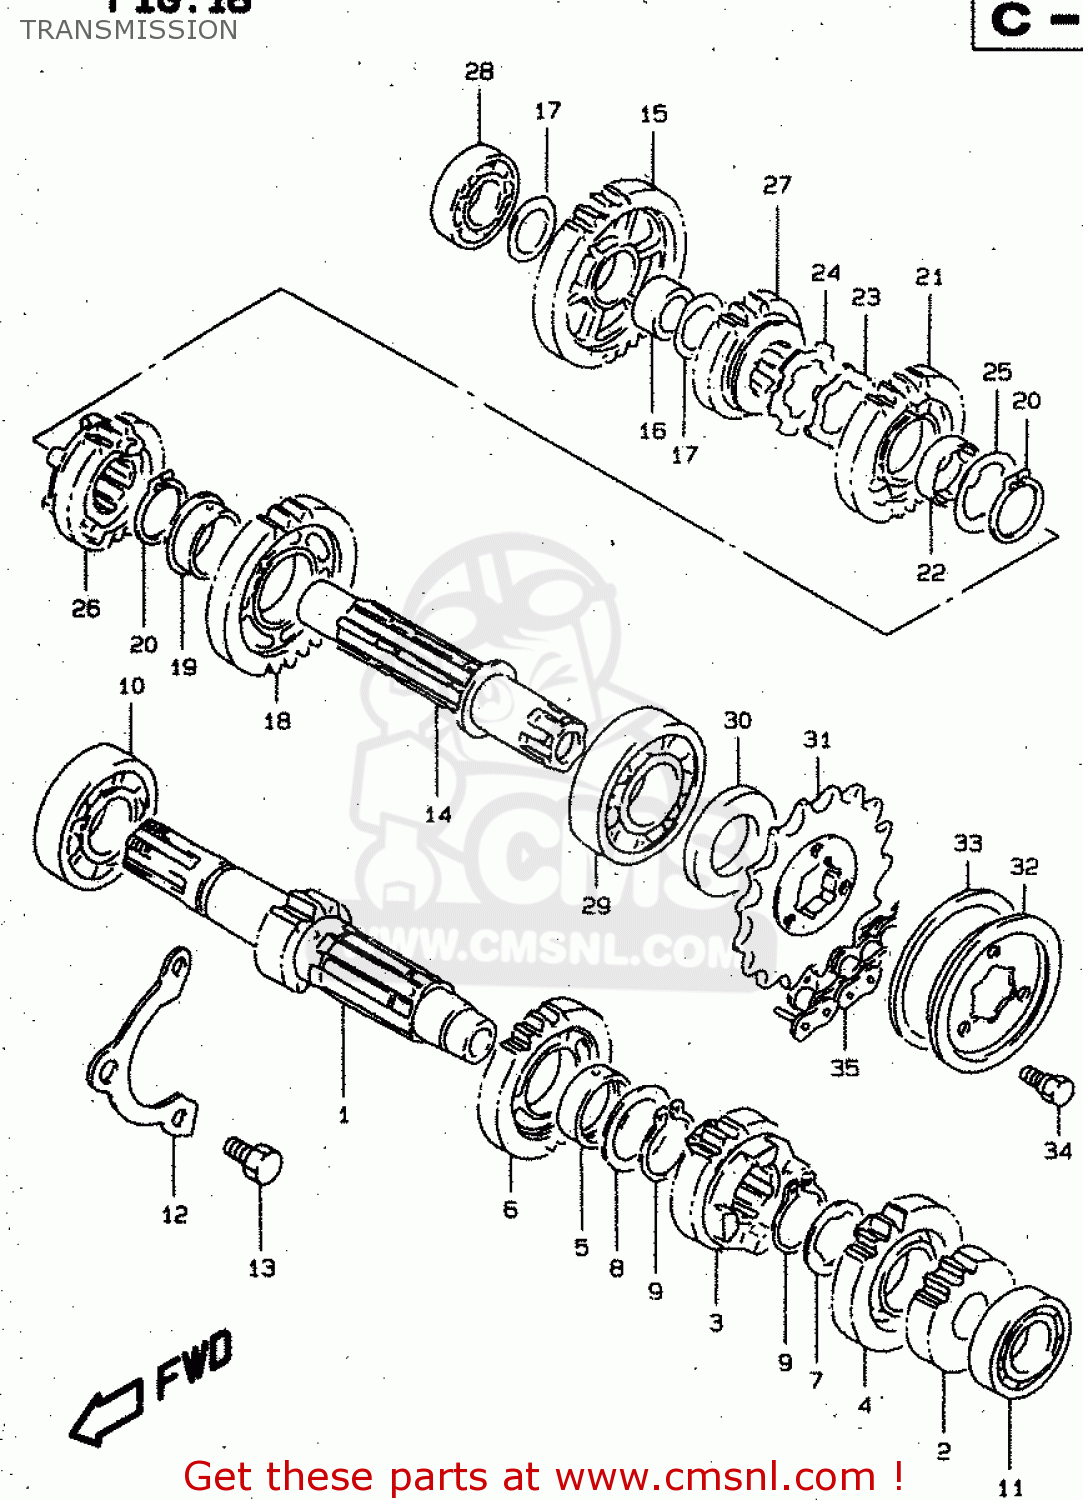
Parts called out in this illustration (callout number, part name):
1	SHAFT SET,CNTR
2	GEAR,2ND DRIVE
3	GEAR,THIRD DRIVE
4	GEAR,4TH DRIVE
5	BUSHING 25X29X10
6	GEAR,5TH DRIVE
7	WASHER,LOCK
8	SHIM(25X34X1)
9	RING,SNAP
10	BEARING(22X56X16)
11	BEARING(17X40X12)
12	RETAINER,CNTR SHAFT BEARING
13	BOLT
14	SHAFT,DRIVE
15	GEAR,1ST DRIVEN
16	BUSH(20X24X13)
17	SHIM(20X30X1)
18	GEAR,2ND DRIVEN
19	BUSH
20	RING,SNAP
21	GEAR,3RD DRIVEN
22	BUSHING
23	WASHER
24	WASHER,LOCK
25	WASHER,LOCK
26	GEAR,4TH DRIVEN
27	GEAR,5TH DRIVEN
28	BEARING(20X42X12)
29	BALL BEARING 25X62X17
30	SEAL,OIL(25X44X7)
31	SPROCKET,ENGINE(15T)
32	PLATE,ENGINE SPROCKET
33	DAMPER,ENGINE SPROCKET
34	BOLT(6X13)
35	CHAIN,DRIVE(DID525V9,110L)
